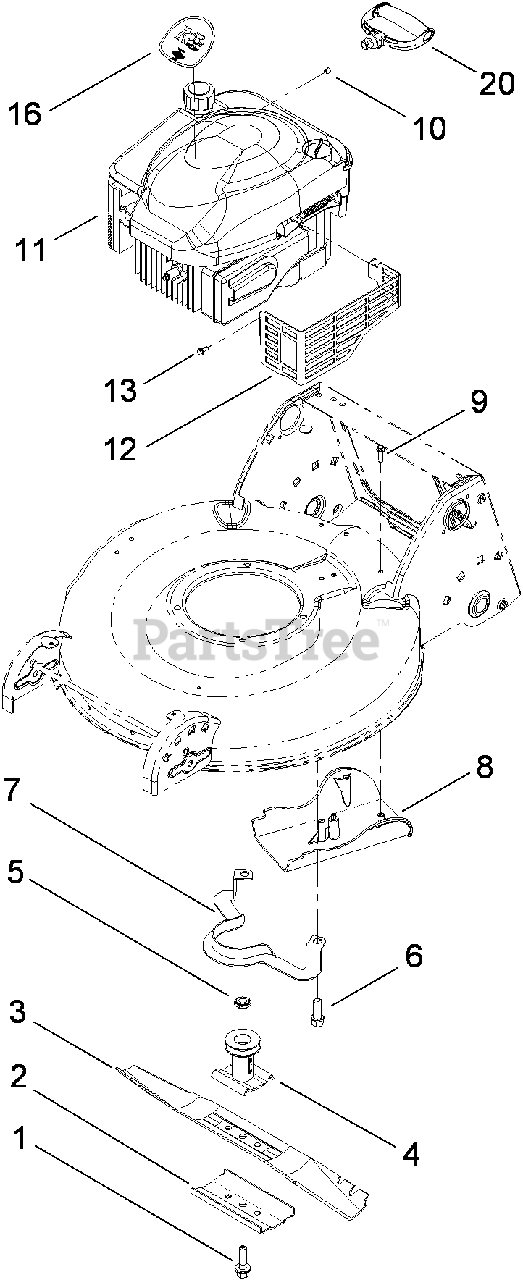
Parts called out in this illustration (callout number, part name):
1	BOLT-BLADE
2	SUPPORT-BLADE
3	BLADE-21 INCH
4	BLADE DRIVER ASM
5	Spacer-Driver
6	SCREW-TAPTITE
8	COVER-BELT
9	SCREW-HWH
10	STOP-ROPE
12	SHIELD-MUFFLER
13	SCREW-TAPTITE
16	DECAL-ENGINE
20	HANDLE-RECOIL
